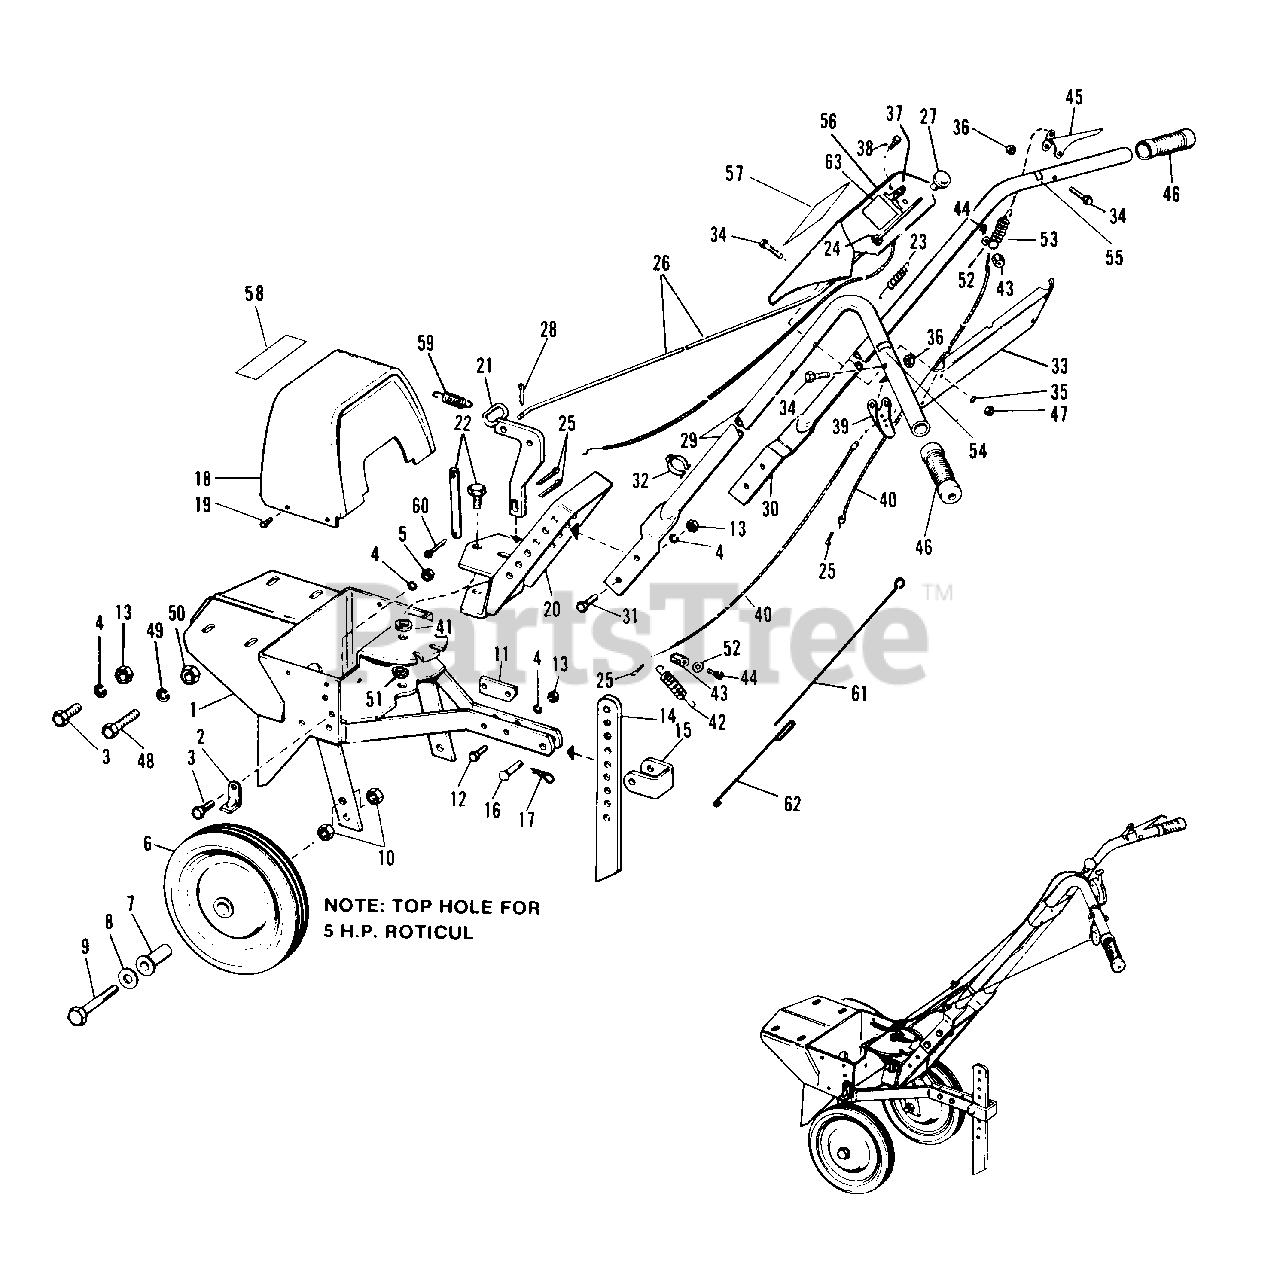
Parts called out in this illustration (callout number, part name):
1	BODY ASSY
3	CAPSCREW, Hex Hd., 3/8-16 x 3/4
4	LOCKWASHER, 3/8
5	LOCKWASHER, 3/8
5	NUT, Hex, Full, 3/8-16
6	WHEEL & TIRE ASSY
7	BUSHING, Wheel
8	WASHER, Plain, 1/2
9	CAPSCREW, Hex Hd., 1/2-13 x 3-1/4
10	NUT, Hex, Jam, 1/2-13
11	PLATE, Stop
12	CAPSCREW, Hex Hd., 3/8-16 x 1-1/2
13	NUT, Hex, 3/8-16
14	BAR, Depth
17	CLIP, Spring
19	SCREW, Washer Hd., Thd. Form, 1/4-20
20	SUPPORT ASSY, Handle
21	LATCH ASSY
22	CAPSCREW, Hex, 1/2-20 x 1-1/4
25	PIN, Cotter, 3/16 x 1
26	ROD, Latch
27	KNOB, Latch Rod
28	PIN, Cotter, 3/32 x 3/4
29	HANDLE, L.H. (990938 only)
29	HANDLE, L.H.
30	HANDLE, R.H. (990938 only)
30	HANDLE, R.H.
31	CAPSCREW, Hex Hd., 3/8-16 x 1
32	CLIP, Cable
33	COVER, Handle Bar
34	CAPSCREW, Hex Hd., 1/4-20 x 1-1/2
35	LOCKWASHER, 1/4
36	NUT, Hex, Full Lock, 1/4-20
37	THROTTLE ASSY, Control
38	SCREW, Self-Tapping, 1/4-20 x 1/2
38	SCREW, Self-Tapping, #10-24
39	GRIP, Clutch, Reverse
41	WASHER, Plain, 1/2
43	CLAMP, Wire
44	SETSCREW, #10-24 x 1/2
45	GRIP, Clutch, Forward
46	GRIP, Handle Bar
47	NUT, Hex, Full, 1/4-20
48	CAPSCREW, Hex, 7/16-20 x 1-1/4
49	LOCKWASHER, 7/16
50	NUT, Hex, Full, 7/16-20
51	NUT, Hex, Full Lock, 1/2-20
52	WASHER, #10 Plain
53	SPRING
54	DECAL, Reverse
55	DECAL, Forward
56	HOUSING, Control
57	EMBLEM, "S"
58	DECAL, Simplicity
59	SPRING
60	PIN, Cotter
61	CLUTCH ROD, Ext.
62	WIRE EXT.
63	DECAL Instructional
